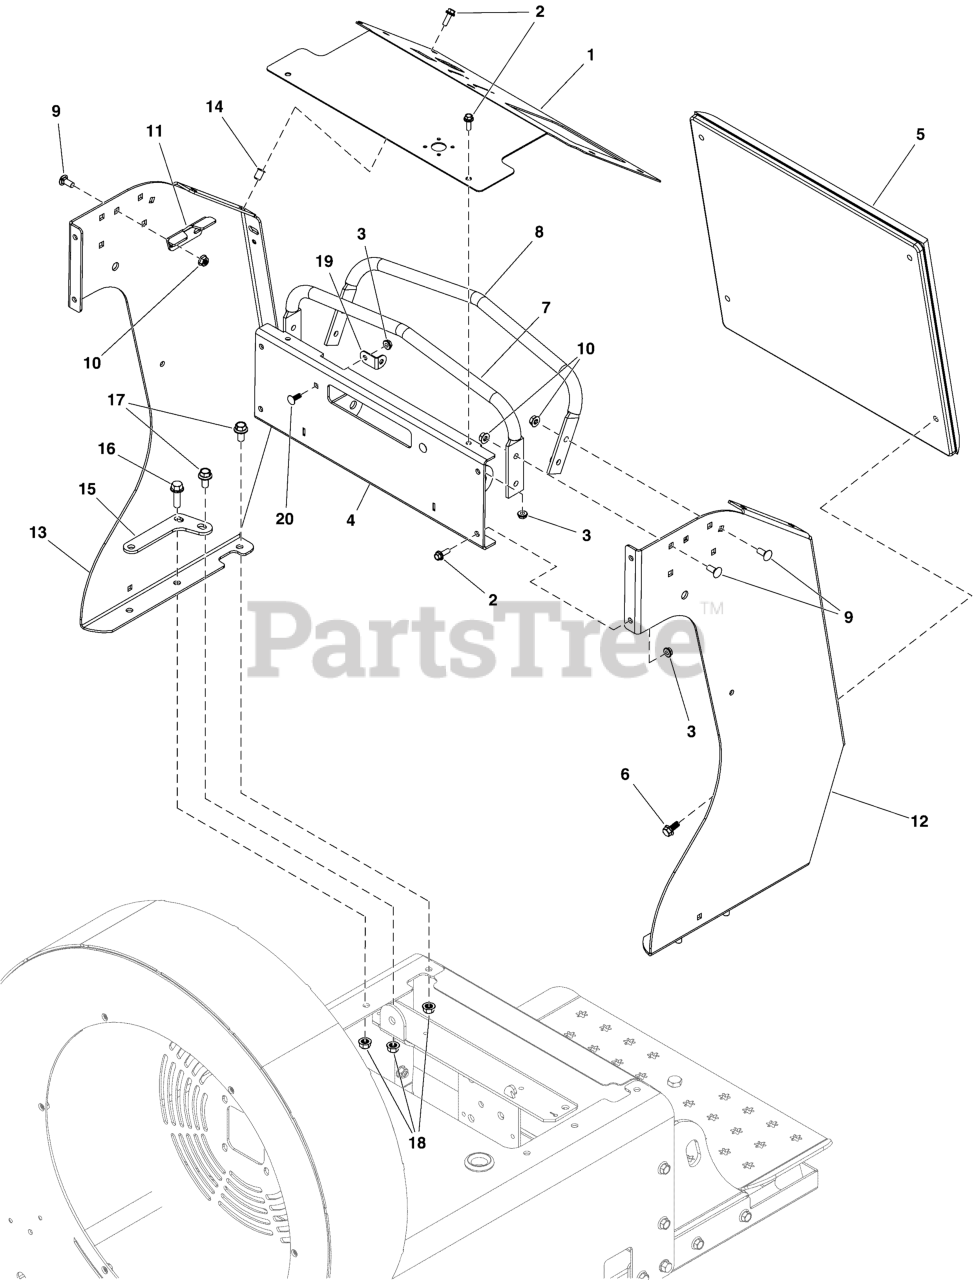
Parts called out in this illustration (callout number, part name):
1	PLATE, DASH PANEL, NEW WITH DECALS
2	BOLT, 1/4-20 X 3/4, FLANGE, CZ
3	NUT, 1/4-20 HEX SERR. FLANGE
4	WELD, DASH FRONT PANEL - ORG
5	KNEE PAD, BLWR
6	SCREW, 5/16-18x0.750, GR5, WHIZ-LOCK, ZC
7	FRONT HANDLE, BLWR - BLK
8	REAR HANDLE, BLWR - BLK
9	BOLT, 5/16-18 X 3/4, CARRIAGE, GD5, CZ
10	NUT, 5/16-18 HEX SERRATED FLANGE (SMALL)
11	BRACKET, NEUTRAL CENTERING, CZ
12	CONTROL TOWER X3, LH - ORG
13	CONTROL TOWER X3, RH - ORG
14	NUT, 1/4-20, RIV, CZ
15	PLATE, UPPER BEAM MOUNT - BLK
16	BOLT, 3/8-16 X 1, FLANGE, GD 5, CZ
17	BOLT, 3/8-16 X 1, FLANGE, GD 5, CZ
18	NUT, 3/8-16, FLANGE, SERRATED UNDER HEAD
19	BRACKET, L HEADLIGHT MOUNT - BLK
20	BOLT,1/4-20X0.750,GR5,STD NECK,SQ,ZC/CL
